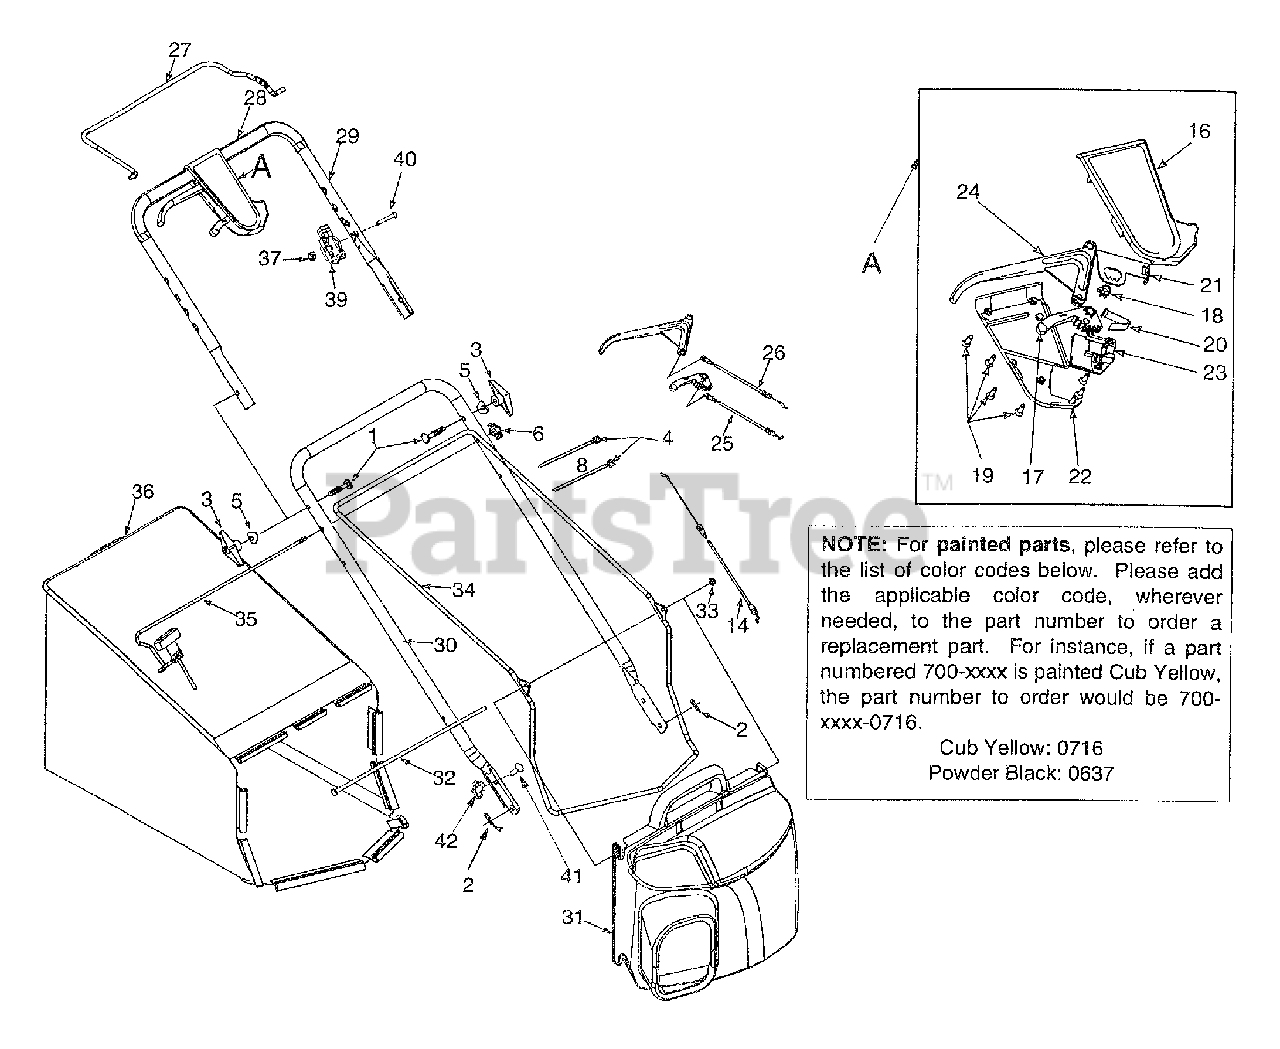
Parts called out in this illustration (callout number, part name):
1	Bolt Cur. Carr. 5/16-18 x 2.0
2	Cotter Pin .072 x 1.12 L.g.
3	Wingknob 5/16-18
4	Strap 4.3 Lg.
5	Wash. Sad. 320 ID x .830 OD
6	Handle Knob, 1/4-20
8	Screw 1/4-20 x 1.3
14	Control Cable 44" Lg.
16	Upper Control Housing
17	6 Speed Shift Lever
18	Gear Insert
19	C Sunk Tap Screw #10-16 x .625
20	Shift Lever Spring
21	6 Spd. Rack Cable Brkt.
22	Lower Control Housing
23	Cable Mounting Cap
24	Control Lever
25	6 Spd. Cable
26	Self Prop. Cable 52"
27	Deluxe Control Handle
28	Foam Grip
31	Grassbag Cover
32	Pivot Rod
36	Grassbag
37	Hex Lock Nut, 1/4-20
39	Control Box
40	Screw 1/4-20 x 1.31
41	Carriage Bolt
42	Wing Nut
